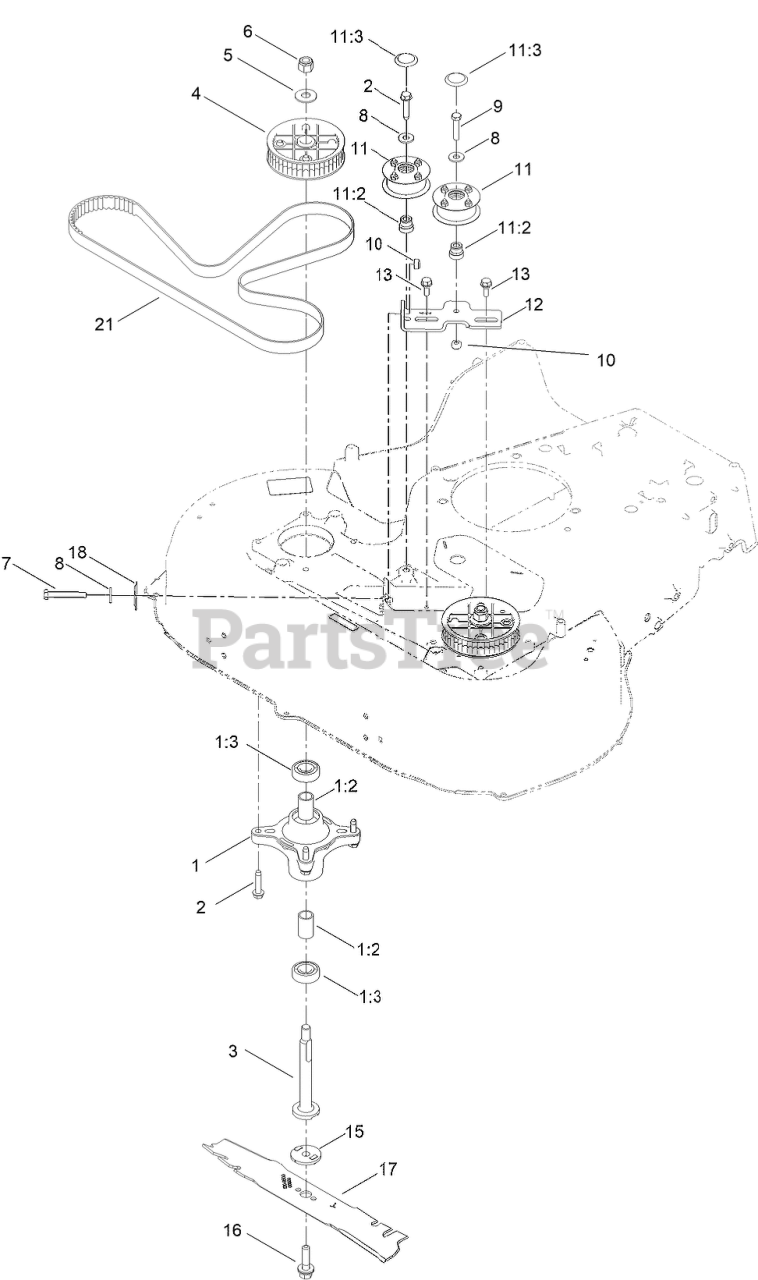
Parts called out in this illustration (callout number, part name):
1	SPINDLE ASM
1:2	SPACER
1:3	BEARING-BALL
2	SCREW-THD ROLL, HWH
3	SHAFT-SPINDLE
4	SPROCKET
5	WASHER-SPRING
6	NUT-HEX
7	BOLT-HH FT
8	WASHER-FLAT
9	SCREW-HH
10	NUT-HEX
11	PULLEY KIT
11:2	ADAPTER-BORE
11:3	PLUG-CAP
12	BRACKET-IDLER
15	ADAPTER-BLADE
16	BOLT-BLADE
17	BLADE-ROTARY [BLACK]
18	SPRING-FLAT
21	BELT-SYNCHRONOUS
